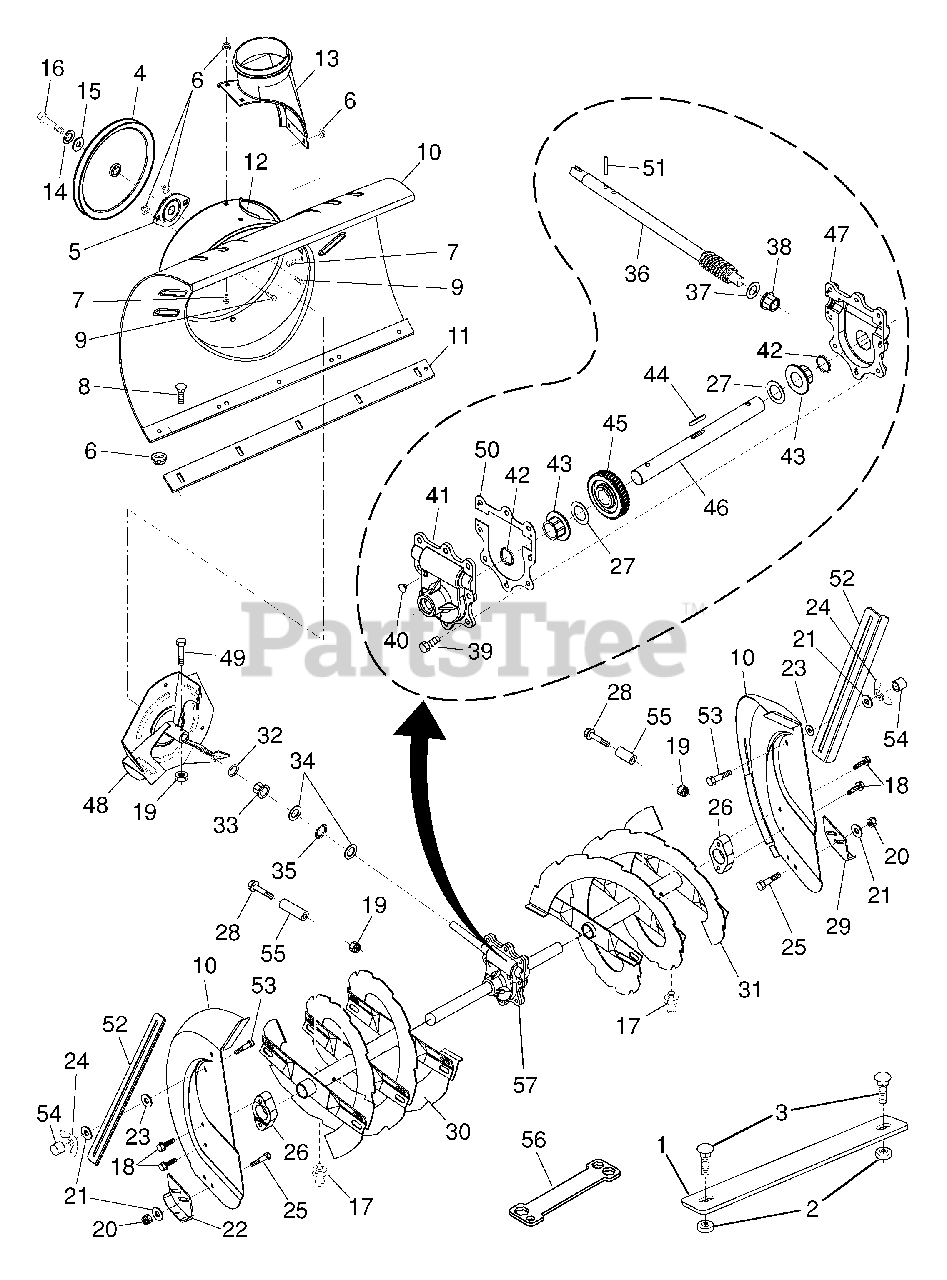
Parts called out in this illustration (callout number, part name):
1	Bar, Weight
2	Nut, Hex 5/16-18
3	Bolt, Carriage 5/16-18 x 1-1/4
4	Pulley, Impeller
5	Bearing Assembly, Flange
6	Nut, Hex Flange 5/16-18
7	Bolt, Flat Head, Carriage 5/16-18 x 5/8
8	Bolt, Carriage 5/16-1 8 x 5/8
10	Housing, Auger
11	Bar, Scraper
12	Bracket, Corner Discharge
13	Base, Discharge Chute
14	Washer, Lock 5/16
15	Washer, Flat
16	Screw, Hex Head 5/16-18 x 3/4
17	Grease Fitting
18	Screw, Hex Head 5/16 x 1
19	Nut, Hex Lock 1/4-20
20	Nut, Hex Lock 5/16-18
21	Washer, Flat 5/16
22	Skid Plate, Heavy Duty
25	Bolt, Shoulder 1/4-20
26	Bearing, Auger
27	Washer, Thrust, 1"
28	Bolt, Shear
29	Skid Plate, Heavy Duty
30	Auger Assembly, RH
31	Auger Assembly, LH
33	Bushing, Flange 3/4
34	Washer, Thrust 3/4
35	Bearing, Thrust 3/4
36	Shaft, Impeller
37	Washer, Thrust 5/8
38	Bushing, Flange 5/8
39	Screw, Hex Head 5/16-18 x 3/4
40	Plug, Case
41	Housing, Gearbox, RH
42	Seal, Oil
43	Bushing, Flange, 1"
44	Key, Square 1/4 x 1/4 x 7/8
45	Gear, Worm
46	Shaft, Auger
47	Housing, Gearbox, LH
48	Impeller Assembly
49	Screw, Hex Head 1/4-20 x 1-5/8
50	Gasket, Gearbox
51	Pin, Roll 3/16 x 1-1/8
52	Bar, Drift
53	Bolt, Hex Head
56	Multi-Wrench
57	Gearbox Assembly
